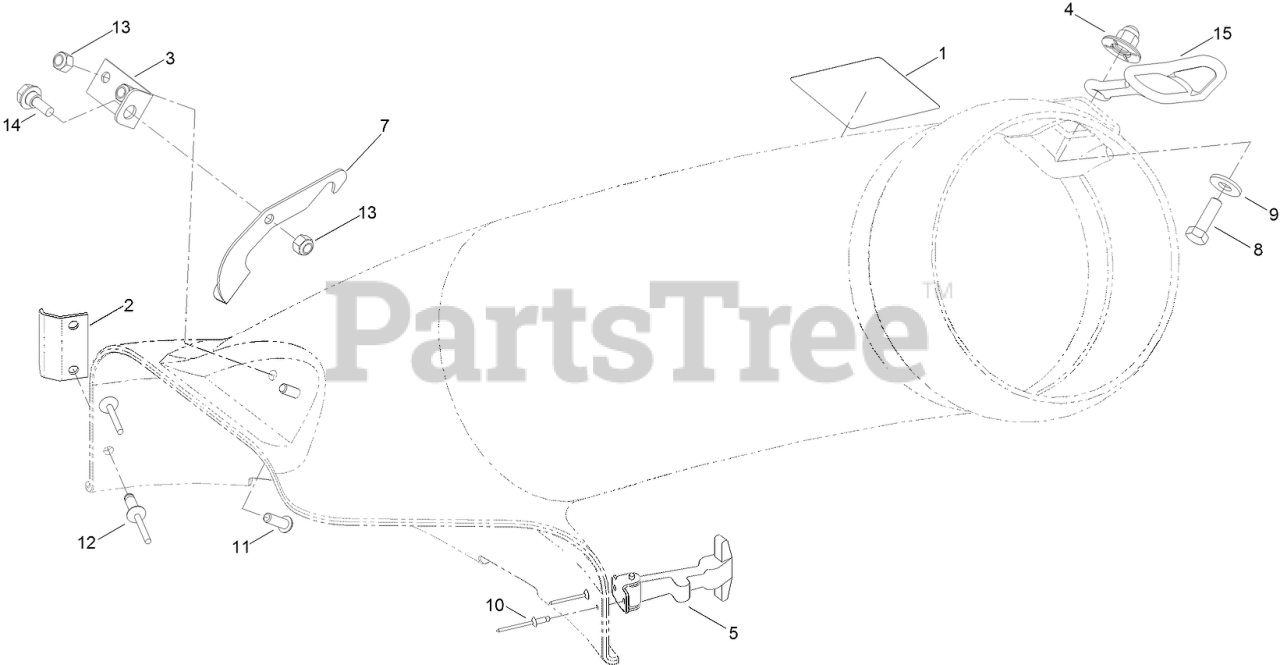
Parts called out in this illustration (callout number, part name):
1	DECAL-DANGER
2	BRACKET-ELBOW
3	PLATE-PIVOT
4	NUT-IMPELLER
5	HANDLE ASM
8	SCREW-HH
9	WASHER-FLAT
10	RIVET-POP
11	SCREW-HSBH
12	RIVET-BLIND
13	NUT-LOCK, NI
14	SCREW-SHOULDER, HHF
15	RETAINER-DUCT
